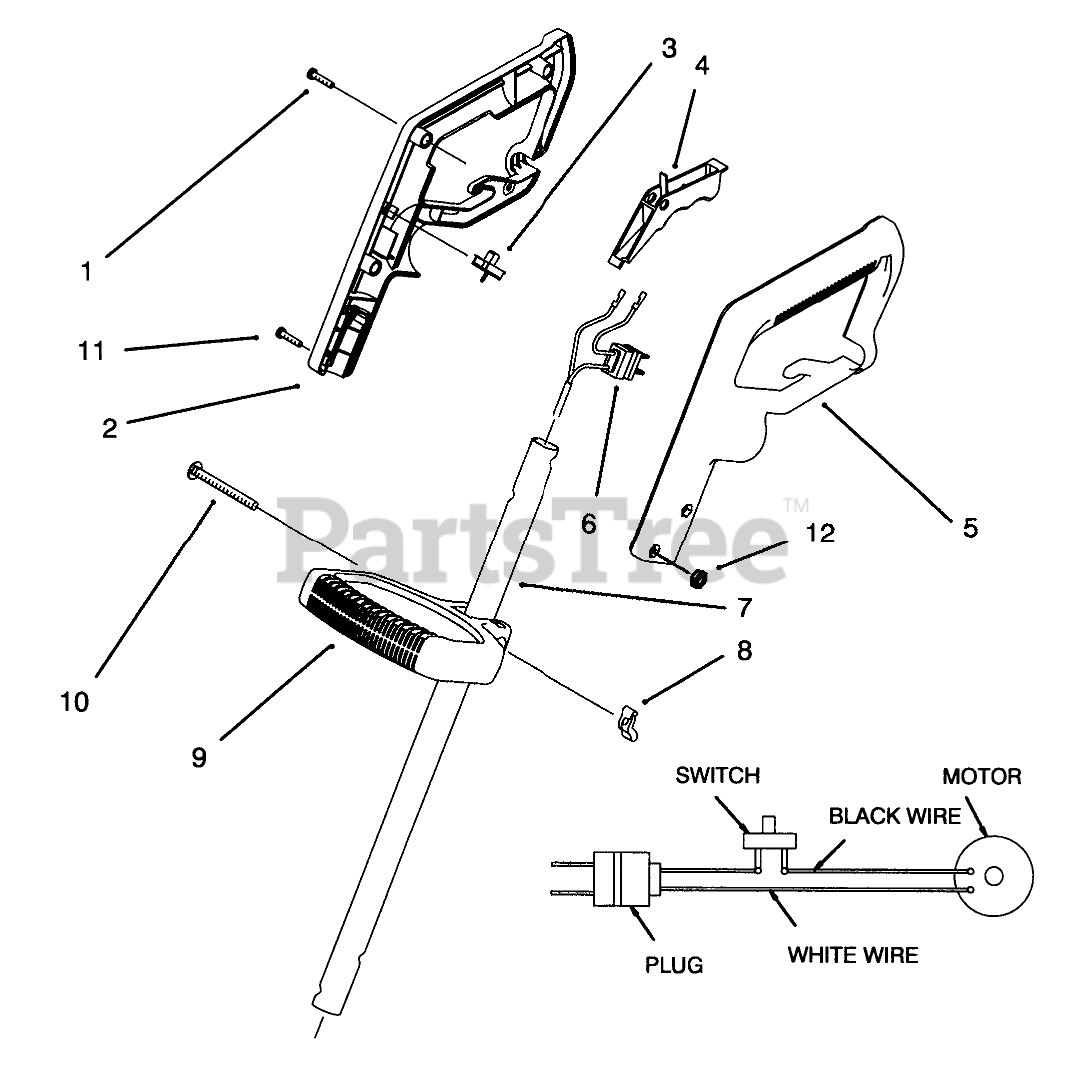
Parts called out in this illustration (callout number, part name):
1	Screw
2	HAND GRIP R.H.
3	SWITCH
4	TRIGGER
5	HAND GRIP L.H.
6	WIRING HARNESS
8	1/4"-20 STAMP WNG NUT
9	MID HANDLE
10	SCREW-CARR.25-20 X 2.50
11	SCREW-PPH
12	NUT-HEX
